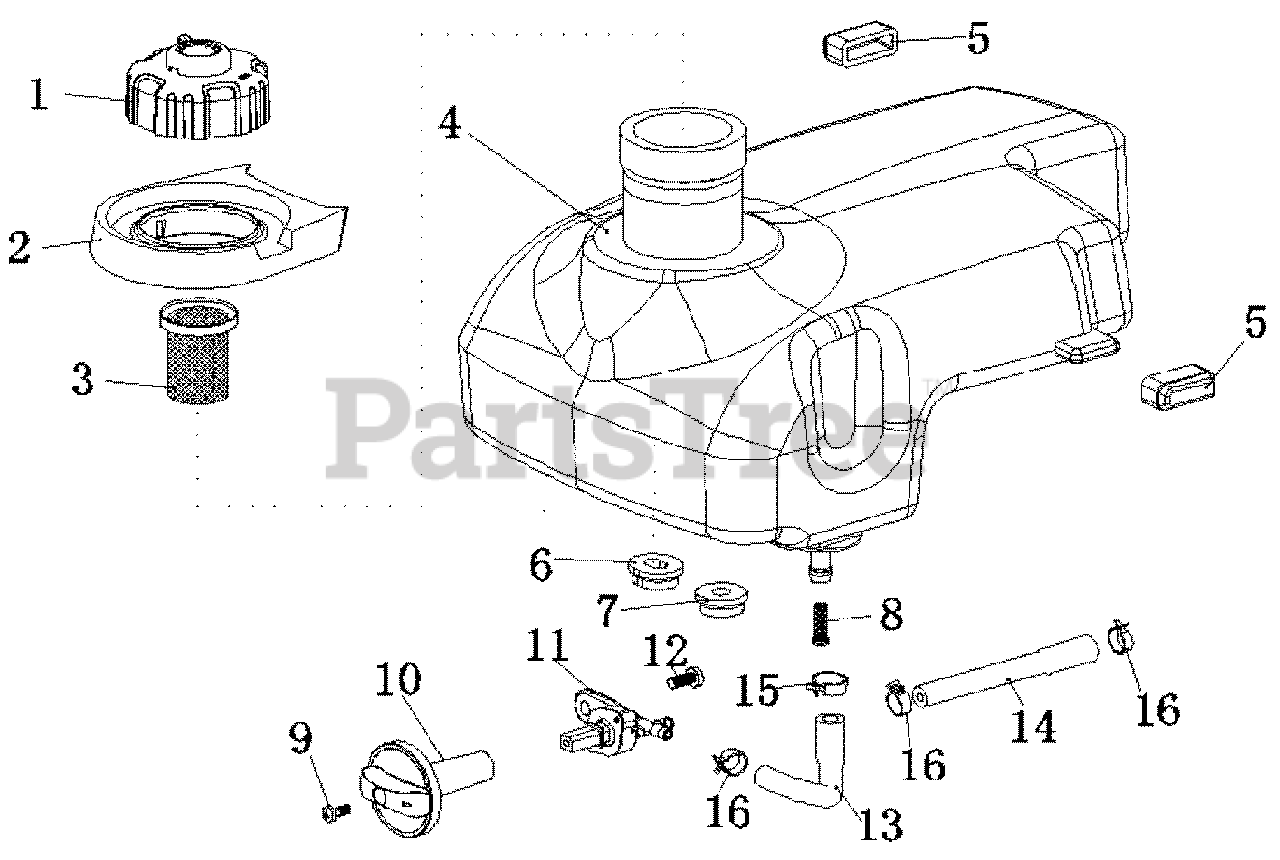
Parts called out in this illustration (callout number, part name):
1	CAP COMP., FUEL FILLER
2	NOTE OIL GUM SET
3	FILTER, FUEL TANK
4	TANK COMP., FUEL
5	RUBBER, FUEL CUSHION
6	RUBBER, FUEL CUSHION
7	RUBBER, FUEL CUSHION
8	FUEL FILTER
9	SCREW M4×10
10	KNOB FUEL SWITCH
11	FUEL SWITCH
12	SCREW FLAT MAT COMBINATION
13	TUBE, FUEL
14	TUBE, FUEL
15	CARD HOOP COMBINATION
16	CARD HOOP COMBINATION
